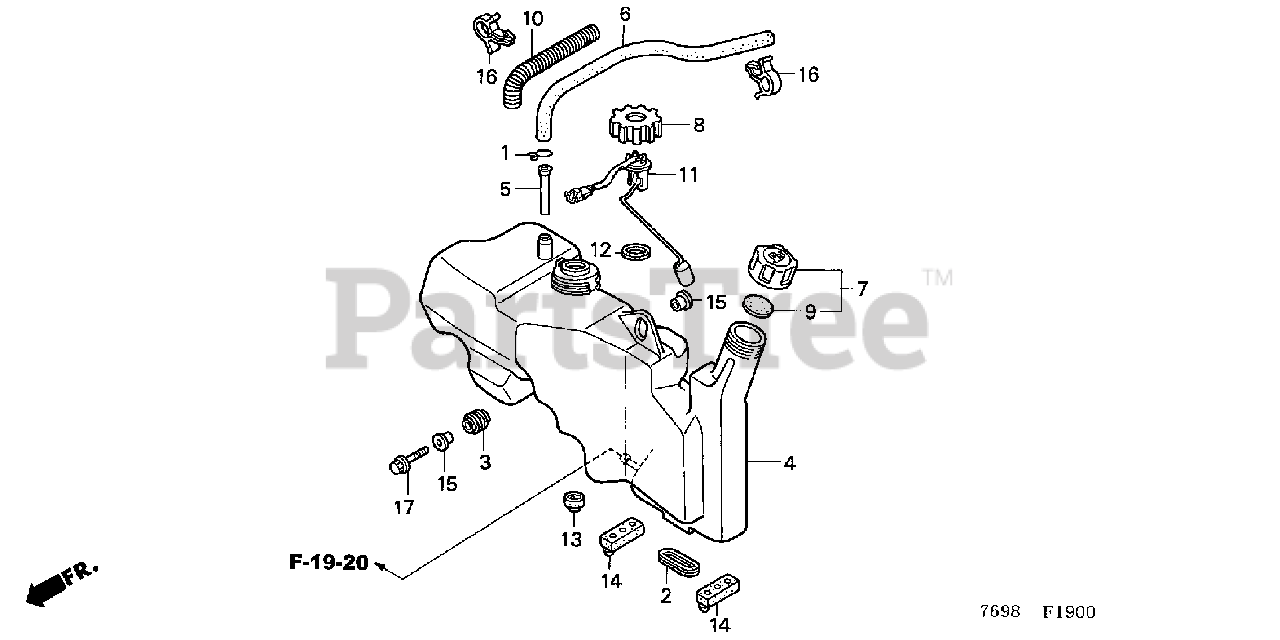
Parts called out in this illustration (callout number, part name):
1	CLIP, OIL DRAIN TUBE
2	GROMMET, TANK SETTING
3	RUBBER, TANK SETTING
4	TANK, FUEL (10L)
5	PIPE, FUEL TANK LEVEL
6	TUBE, FUEL TANK BREATHER
7	CAP ASSY., FUEL TANK
8	BODY, FUEL CAP
9	GASKET, FUEL CAP
10	TUBE, CORRUGATED
12	GASKET, BASE
13	RUBBER, STOPPER
14	RUBBER B, SEAT SETTING
15	COLLAR, FUEL TANK
16	CLIP, TUBE (12MM)
17	BOLT, FLANGE (6X32)
